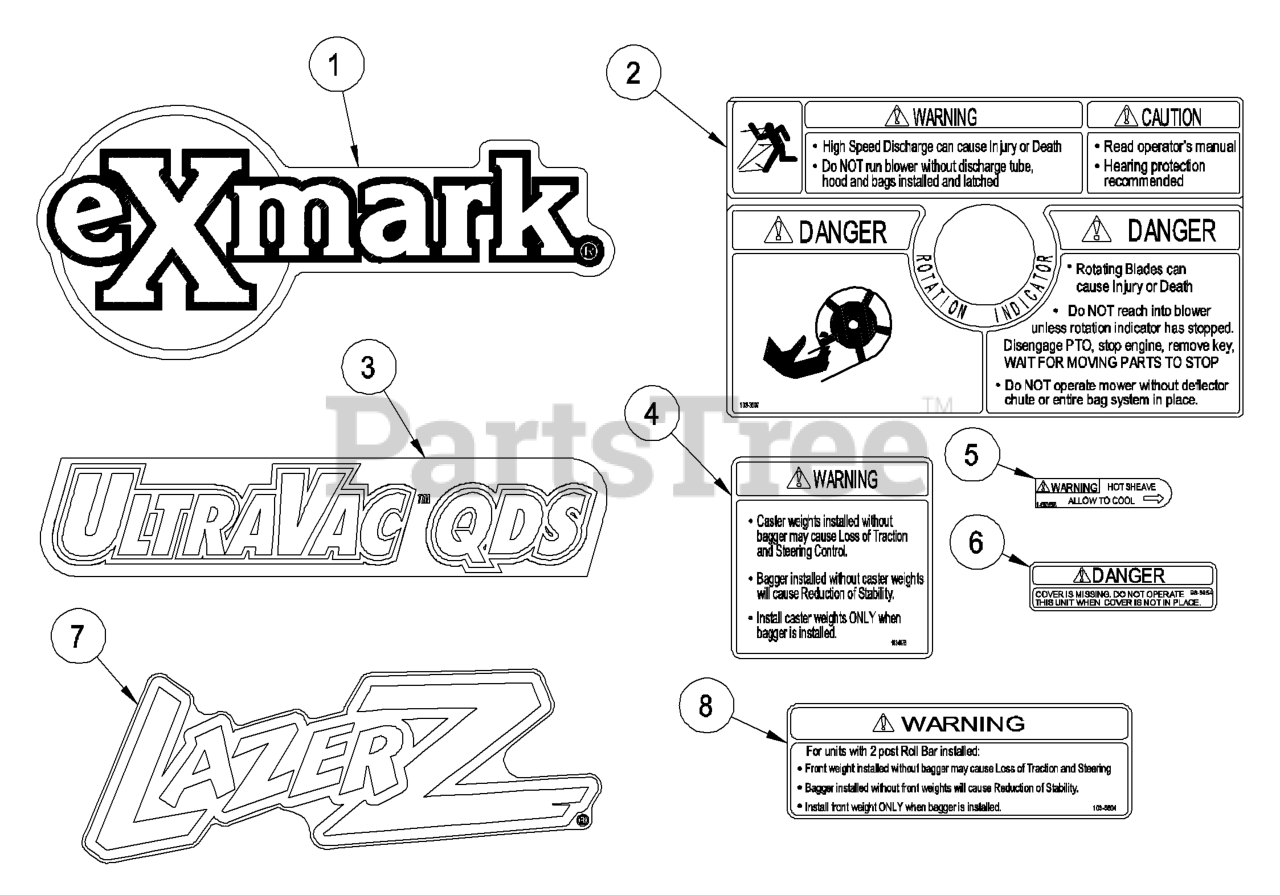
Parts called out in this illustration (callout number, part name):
1	DECAL, EXMARK
3	DECAL, ULTRAVAC QDS
5	DECAL-WARNING
6	DECAL-COVER, MISSING
7	DECAL,LAZER MODEL
